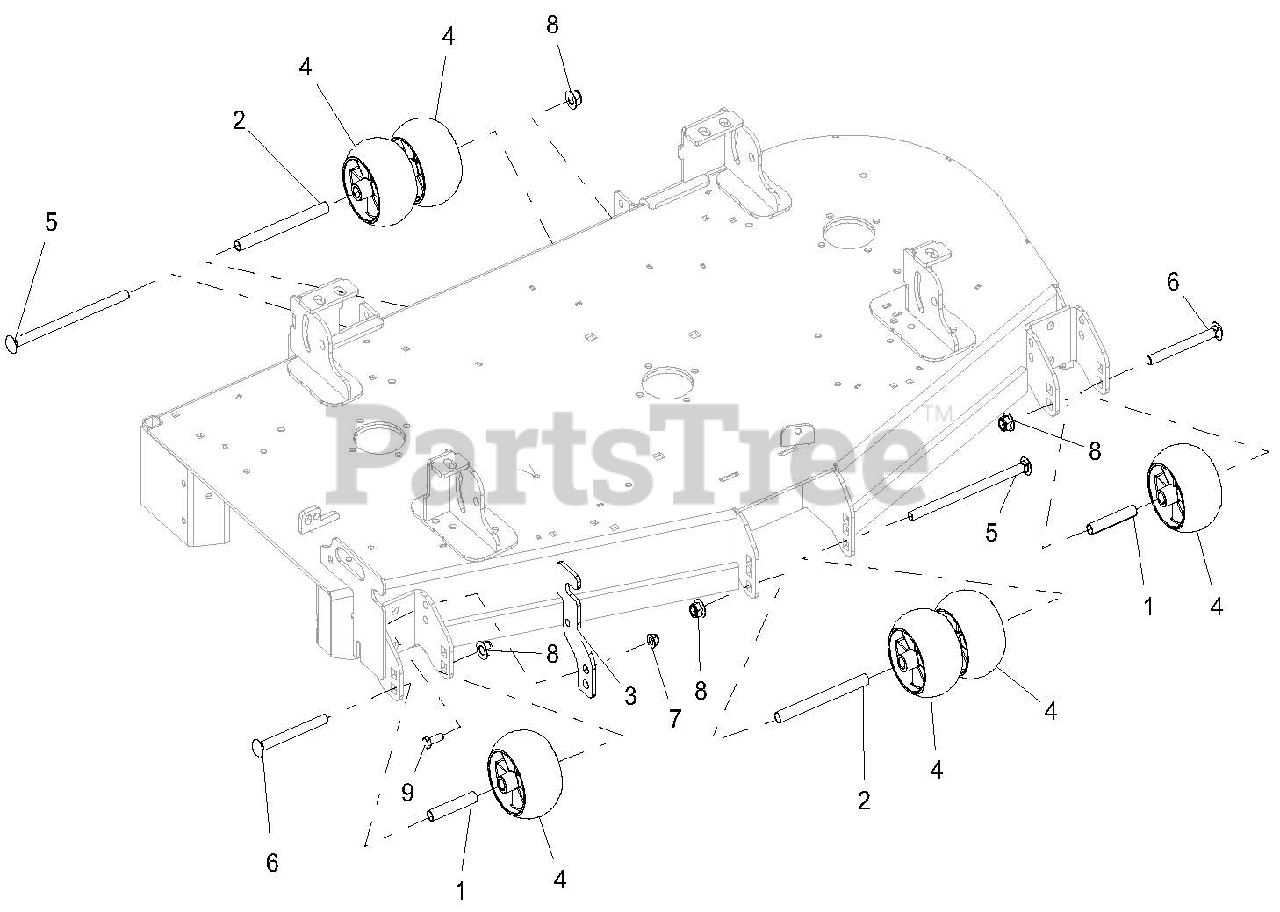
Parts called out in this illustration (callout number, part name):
1	SPACER, .510X.625X3.35
2	SPACER, .510 X .625 X 6.50
3	CHUTE STORAGE BRACKET-RED
4	ANTI-SCALP WHEEL - 5X3 CTR
5	BLT-RDHDSQNK .50-13X8.50Y
6	BLT-RDHDSQNK .50-13X5.00 G5 YWZC
7	NUT-LK-NYL-FLG .38-16 YWZC
8	NUT-LK-NYL-FLG .50-13 YWZC
9	BLT-HEX .38-16X1.00 GR5 YWZC
